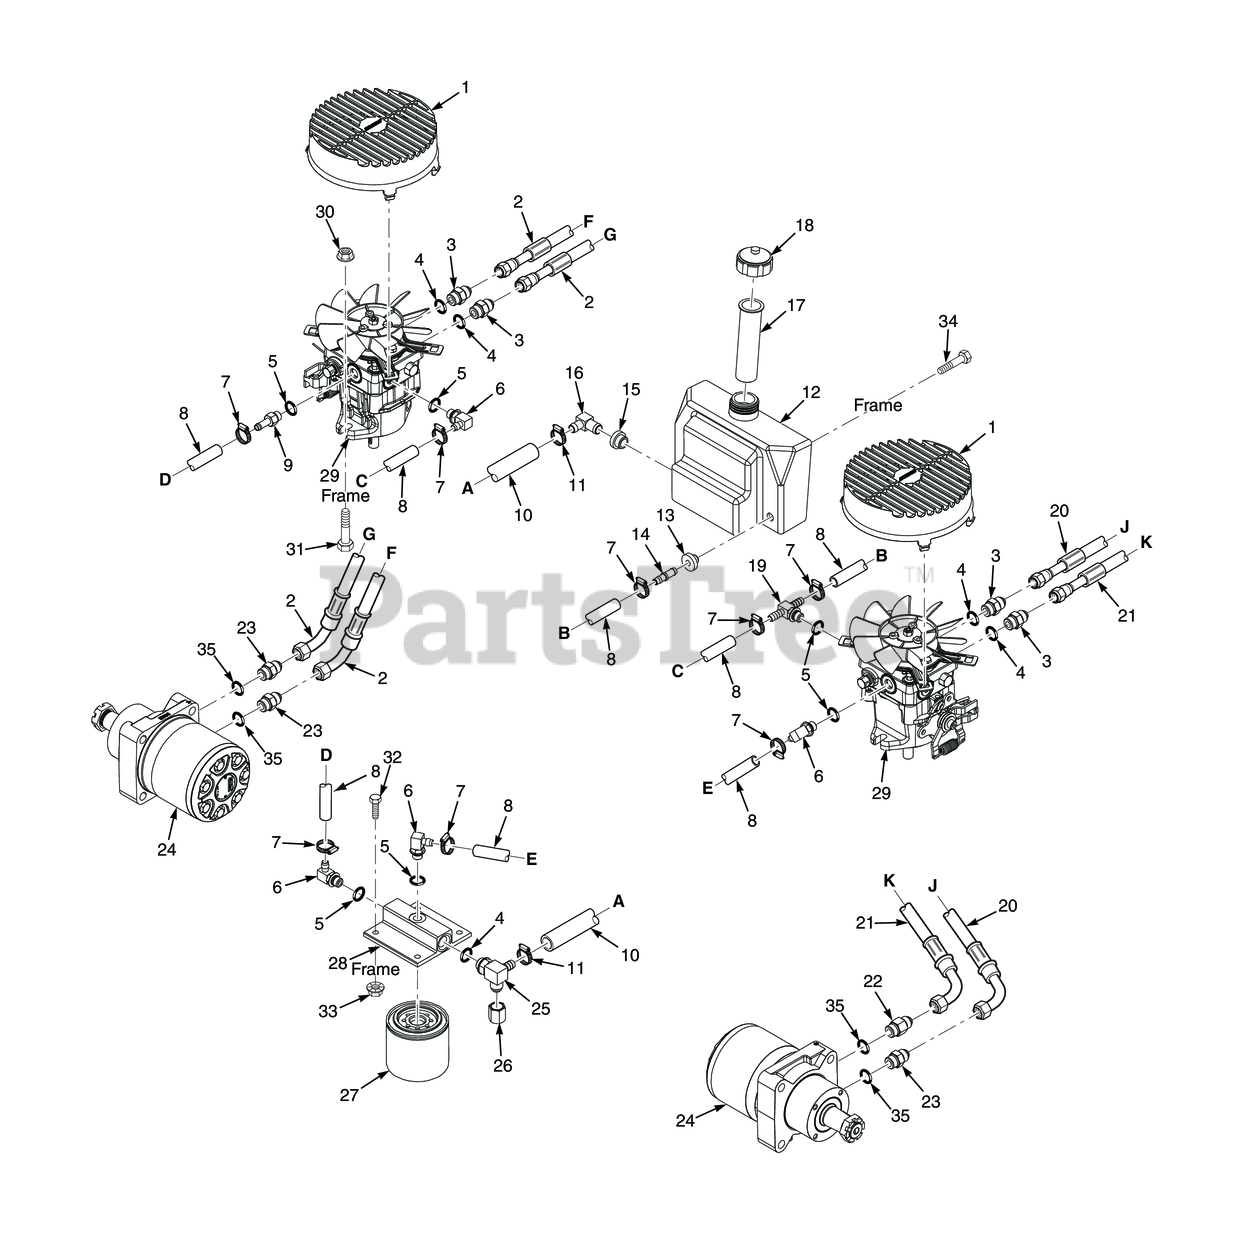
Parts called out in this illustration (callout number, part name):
1	Fan Cover, Pump
2	Hose Assembly
3	Union, 3/4"-16 JIC x 3/4"-16 O-Ring
4	"O" RING, 3/32 X 5/8" ID
5	"O" RING, 5/64 X 15/32 ID
6	Elbow, 90 Degree - 9/16" O-Ring x 3/8" Hose
7	Clamp, .69" Max. / .25" Min. Dia.
8	Hose, 3/8" ID - 10-1/4" Long (Order By The Inch)
9	Fitting, 9/16" O-Ring x 3/8" Hose
10	Hose Assembly, 1/2" ID (Oil Reservoir to Filter Base)
11	Clamp, Cable 3/4" I.D.
12	Hydraulic Tank Assy
13	Bushing, 0.56" Dia. Viton
14	Fitting, Straight
15	Bushing, 0.78" Dia. Viton
16	Fitting, 90 Degree - 1/2" Hose
17	Insert, Filler Neck
18	CAP, HYDRAULIC TANK
19	Tee Fitting, O-Ring to Barb
20	Hose Assembly
21	Hose Assembly
22	Fitting, 1/2" JIC x 5/8" O-Ring (LH Wheel Motor - Upper Port Only)
23	TUBE UNION, 3/4-16 JIC TO 7/8-14 "O" RING
24	Wheel Motor, Parker
25	Tee, 3/4" O-Ring x JIC x 1/2" Hose
26	CAP, 3-4-16 JIC
27	OIL FILTER, SPECIAL
28	Filter Head Assembly
29	Pump, LH (PK-3KCC-GA1F-XXXX)
29	Pump, RH (PK-3HCC-GA1F-XXXX)
30	Nut, Flange Elastic Stop Nut, 3/8-16
31	Bolt, Hex Head, 3/8-16 x 1-1/2"
32	BOLT, SERRATED FLANGE HEX HEAD 5/16-18 X 3/4"
33	Nut, Serrated Flange 5/16-18 (Right Front Engine Mounting, Briggs and Kohler Only)
34	CAP SCREW, 5/16-18 X 1/2" SERRATED FLANGE HEX
35	"O" RING, 3/32 X 3/4 ID
